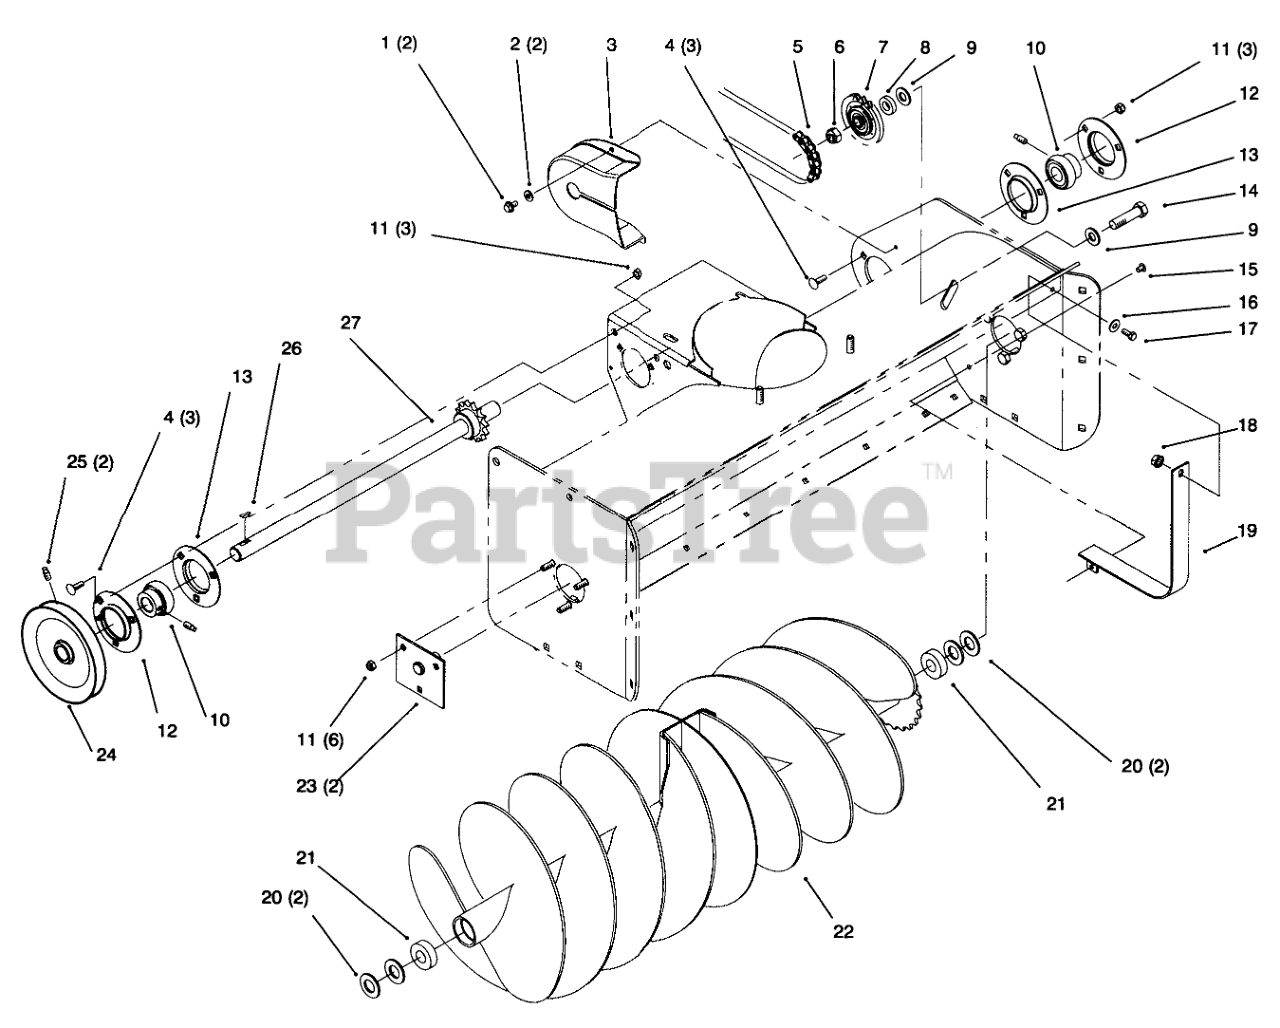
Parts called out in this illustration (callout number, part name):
1	SCREW-HWH
2	WASHER-FLAT
3	GUARD-CHAIN
4	BOLT-CARR
5	CHAIN-64 PITCHES
6	NUT-LOCK, NI
7	Idler Sprocket
8	SPACER
9	WASHER-FLAT
10	BEARING AND COLLAR
11	NUT-LOCK, NI
12	FLANGE-ZERK RELUBE
13	Flange
14	SCREW-HH
15	SCREW
16	WASHER-FLAT
17	SCREW-HH
18	NUT-KEPS
19	GUARD-INNER
20	WASHER-FLAT
21	BEARING-BALL
22	Auger
23	SUPPORT
24	PULLEY
25	SCREW-SQH
26	Key
27	SHAFT W/SPRKT
